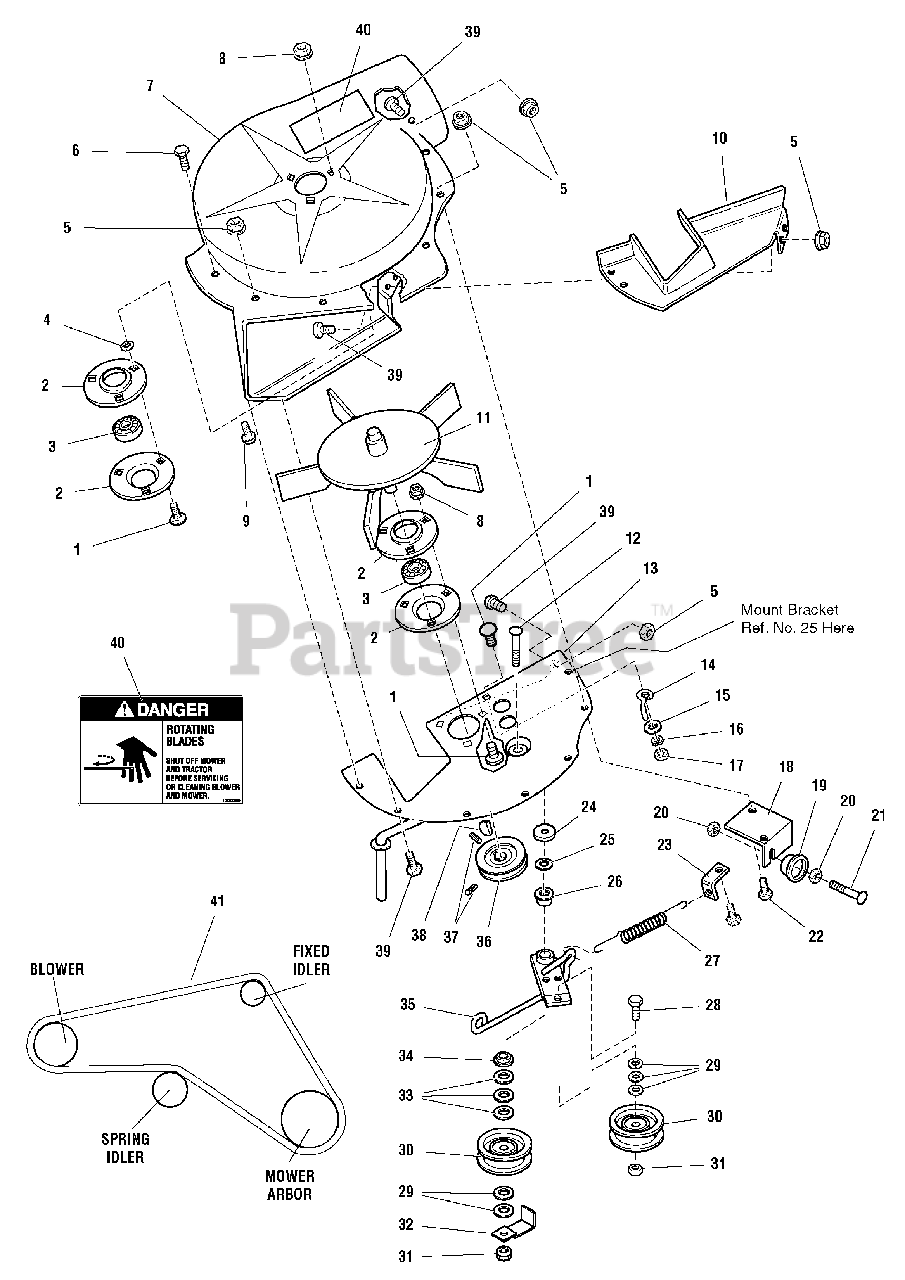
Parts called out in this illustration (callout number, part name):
1	BOLT, Carriage, 5/16-18 x 3/4
2	BEARING, Retainer
3	BEARING
4	PUSH NUT, 3/8
5	NUT, Hex, Flange Lock, 1/4-20
6	CAPSCREW, Hex, Taptite, 1/4-20 x 1/2
7	FAN HOUSING
8	NUT, Flange Whizlock, 5/16-18
9	SCREW, Washer Head, 1/4-18 x 5/8
10	PLATE, Cover
11	FAN ASSEMBLY, 5 Blade
12	BOLT, Carriage, 3/8-16 x 2-1/4
13	PLATE ASSEMBLY
14	BELT STOP
15	WASHER, Flat, 5/16 x 7/8 OD
16	WASHER, Spring Lock, 5/16
17	NUT, Hex, 5/16
18	BRACKET ASSEMBLY, Turbo
19	WASHER, Cup, 0.40 Hole x 1.65 OD
20	NUT, Whizlock, 5/16-18
21	BOLT, Carriage, 5/16-18 x 2-1/2
22	CAPSCREW, Hex Hd., 1/4-20 x 3/4
23	BRACKET, Anchor, Spring
24	WASHER, Plain, 1/2 x 1-3/8 OD
25	PUSHNUT, 3/8
26	SPACER, Idler Arm
27	SPRING, Tension
28	CAPSCREW, Hex Head., 3/8-16 x 1-1/2
29	WASHER, Plain, 3/8 X 7/8 O.D.
30	IDLER PULLEY ASSEMBLY, 2-3/4 OD
31	NUT, 3/8-16
32	BELT STOP
33	WASHER, 3/8 x 1
34	WASHER, 3/8 x 1-1/2 OD
35	LEVER ASSEMBLY, Turbo
36	PULLEY, Driven, 3" OD
37	SETSCREW, Torx Dr, 5/16-18 x 5/16
38	KEY, Woodruff, Modified
39	BOLT, Carriage, 5/16-18 x 3/4
40	DECAL, Danger, Blower
41	BELT, 3L, 36 Long
42	DECAL, Patent
